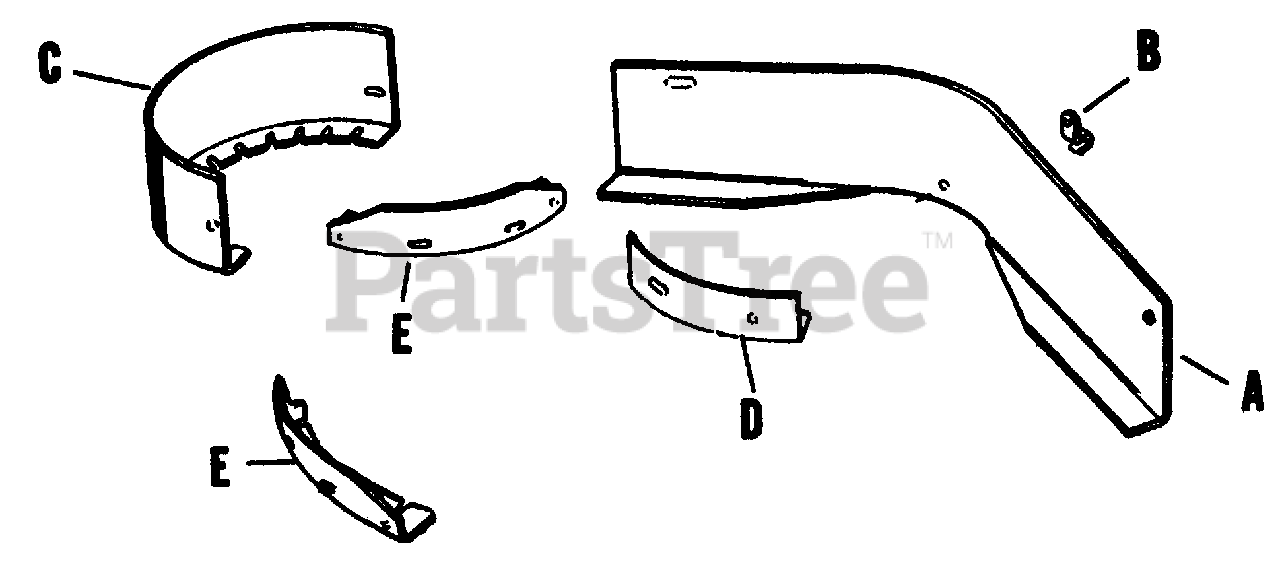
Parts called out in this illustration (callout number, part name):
A	Baffle, Mulcher, Front
C	Baffle, Side
D	Baffle, Rear, Center
E	Baffle, Mulcher, Rear, Side
